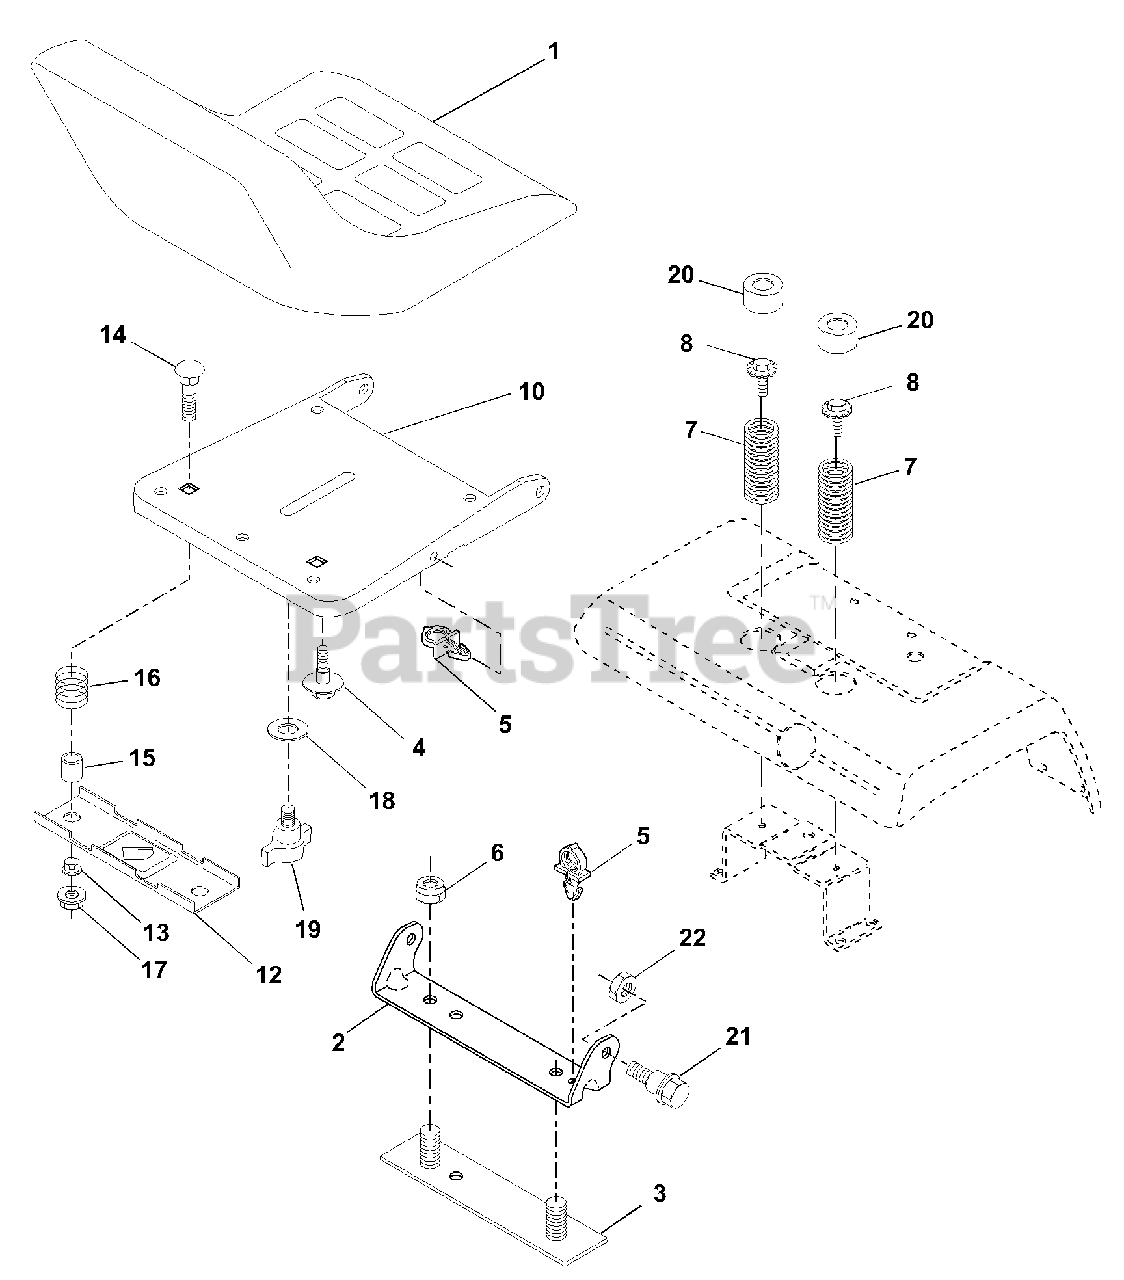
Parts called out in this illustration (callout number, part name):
1	Seat
2	Bracket, Pivot Seat
3	Strap, Fender
4	Bolt, Shoulder 5/16-18 X .62
5	Clip, Push In Hinged
6	Nut, Crownlock 3/8-16
7	Spring, Seat Cprsn
8	Bolt 5/16-18 UNC X 3/4
10	Pan, Seat
12	Bracket, Mounting Switch
13	Bushing, Snap
14	Bolt, Carriage 1/4-20 X 1-1/2
15	Spacer, Split
16	Spring, Cprsn
17	Nut, Lock 1/4 Lge Flg Gr. 5
18	Washer 17/32 X 1-3/16 X 12 Ga.
19	Knob, Seat
20	Cap, Spring Seat
21	Bolt, Shoulder 5/16-18
22	Nut, Crownlock 5/16-18
